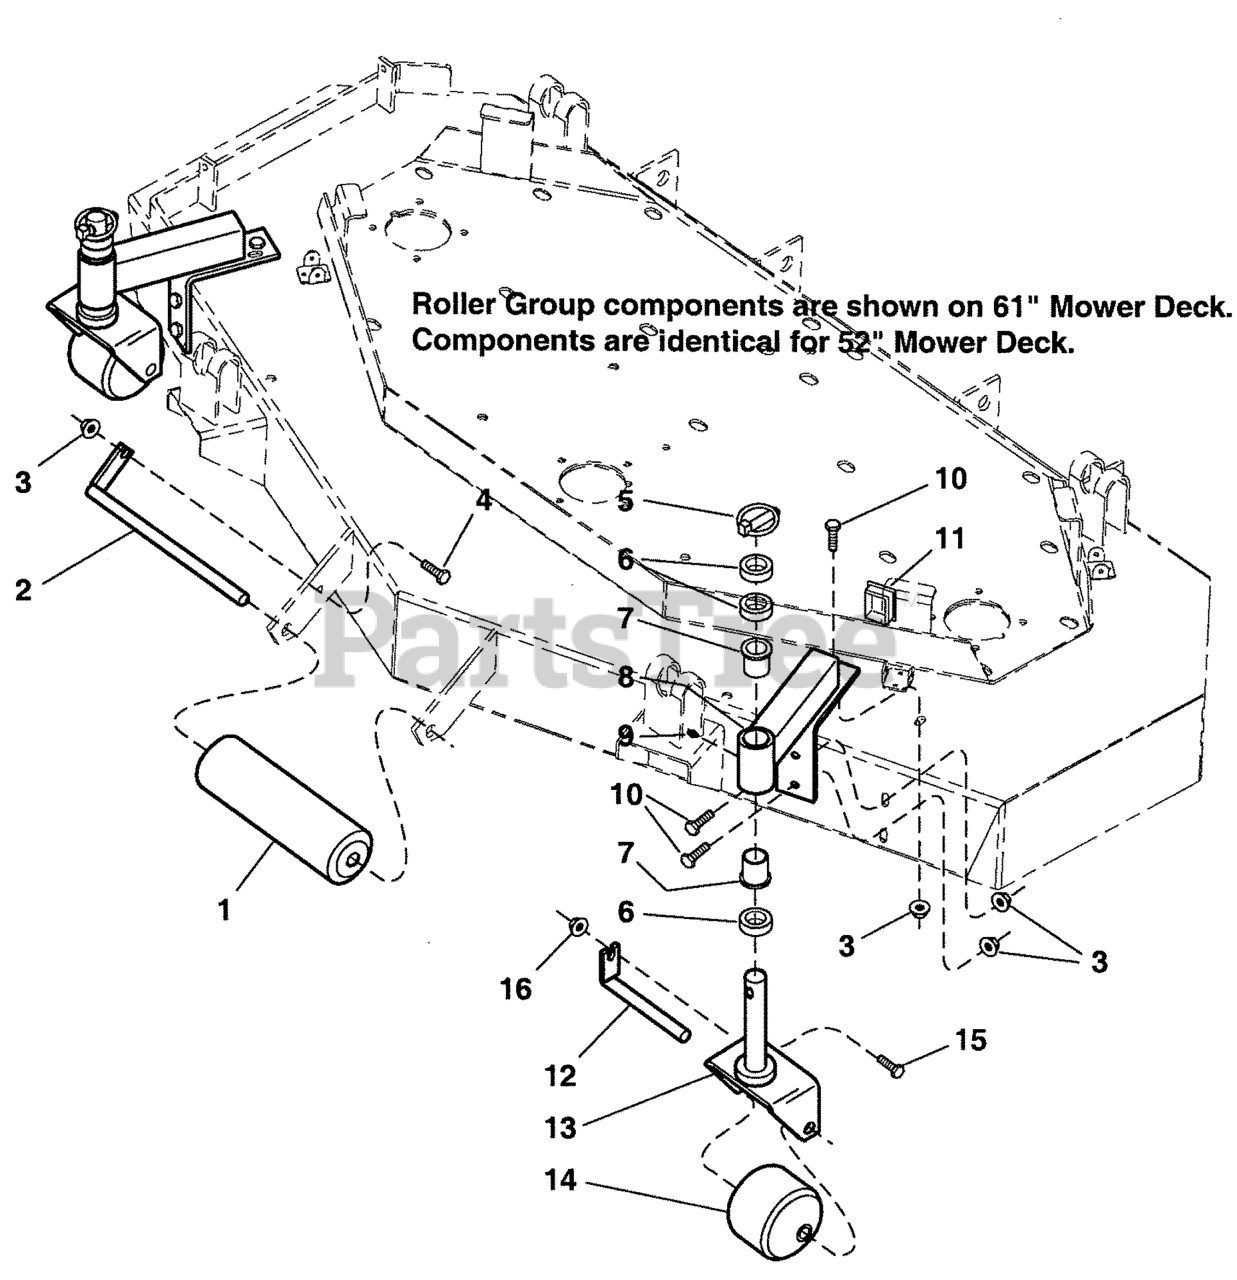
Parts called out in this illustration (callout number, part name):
1	ROLLER, Nose
3	NUT, Hex, Serrated Flange, 3/8-16
4	BOLT, 3/8-16 X 1" GD5 CZ
5	LYNCH PIN
6	SPACER, Caster
7	BUSHING, FLANGE
8	CASTER MOUNT ARM
9	GREASE FITTING
10	BOLT, 3/8-16 X 3/4" GD5 CZ
11	CAP, Plastic
12	CASTER ROLLER PIN
13	CASTER YOKE
14	ROLLER, Caster
15	BOLT, 5/16-18 X 3/4 GD5
16	NUT, 5/16-18 HEX SERRATED FLANGE (SMALL)
